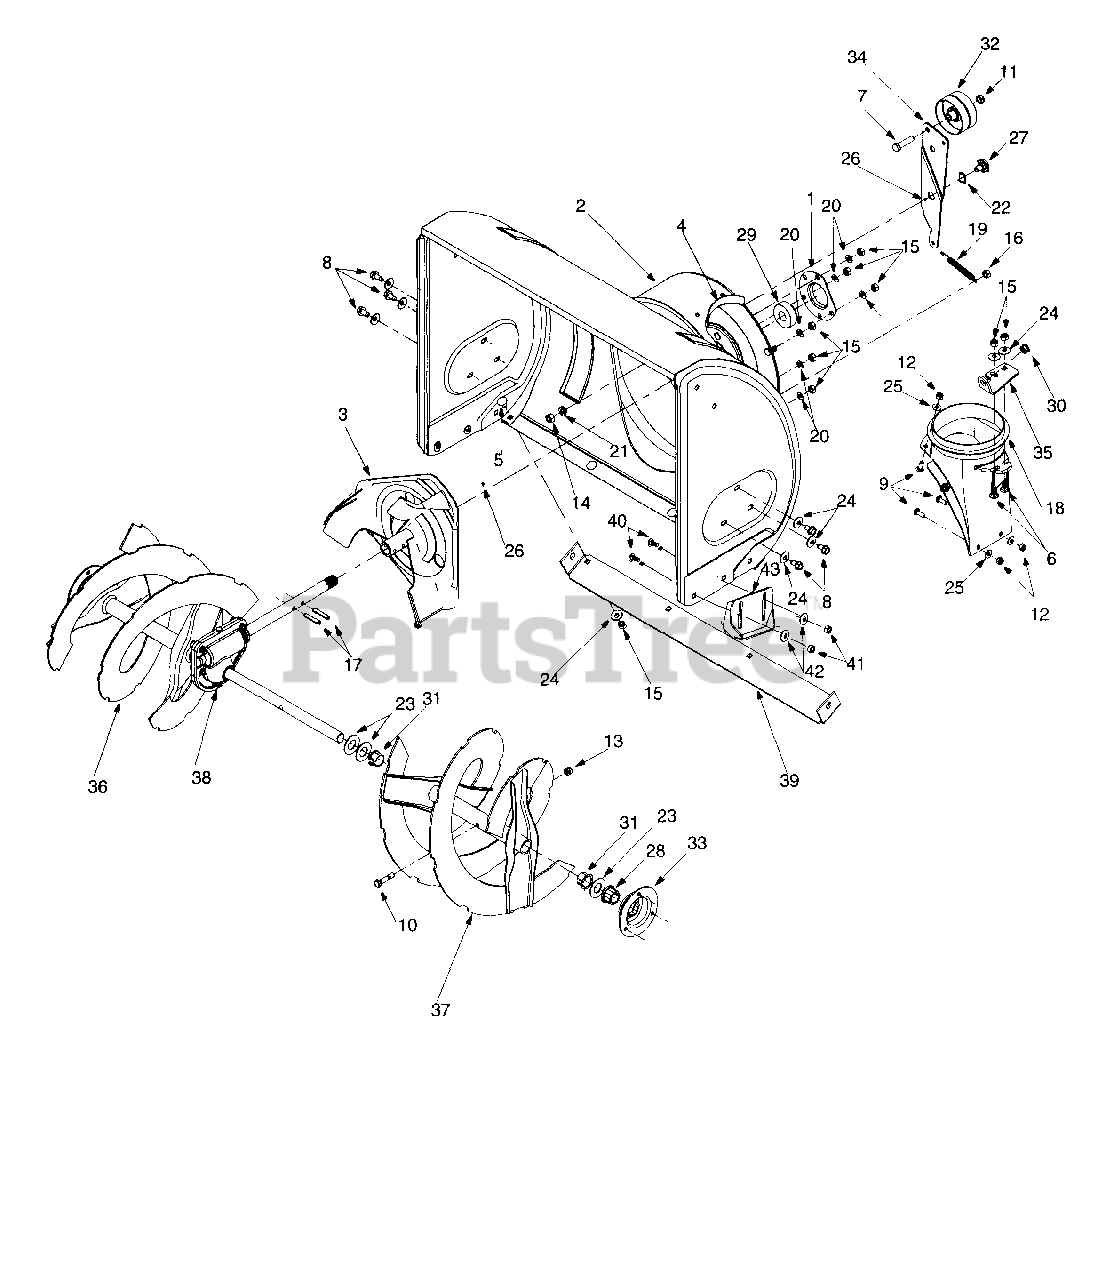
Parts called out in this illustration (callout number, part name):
1	Bearing Housing
5	Carriage Bolt 5/16-18 x .62"
6	Carriage Bolt 5/16-18 x .75" Gr 2
7	Hex Screw 3/8-24 x 1.5" Gr5
8	Hex Washer Head Self-Tapping Screw 5/16-18 x .62"
9	Carriage Screw 1/4-20 x .75"
10	Shear Bolt 5/16-18 x 1.5"
11	Jam Nut 3/8-24
12	Hex Lock Nut 1/4-20
13	Hex Lock Nut 5/16-18
14	Hex Nut 3/8-16 Gr.2
15	Hex Nut 5/16-18 Gr.5
16	Hex Patch Nut 5/16-18
17	Spiral Pin
18	Chute Adapter
19	Extension Spring
20	Lock Washer
21	Lock Washer
22	Wave Washer
23	Flat Washer
24	Belleville Washer
25	Flat Washer
26	Grease
27	Shoulder Screw
28	Hex Flange Bearing
29	Flange Ball Bearing
30	Bushing
31	Flange Bushing
32	Flat Idler
33	Bearing Housing
34	Auger Idler Arm
35	Chute Crank Bracket
36	Spiral Assembly: RH 26"
36	Spiral Assembly: RH 30"
37	Spiral Assembly: LH 26"
37	Spiral Assembly: LH 30"
38	Gear Assembly: Auger 26"
38	Gear Assembly: Auger 30"
39	Shave Plate: Auger 26"
39	Shave Plate: Auger 30"
40	Carr. Bolt: 5/16-18 x 0.75
41	Hex Nut: 5/16-18 Gr.5
42	Beleville Washer
